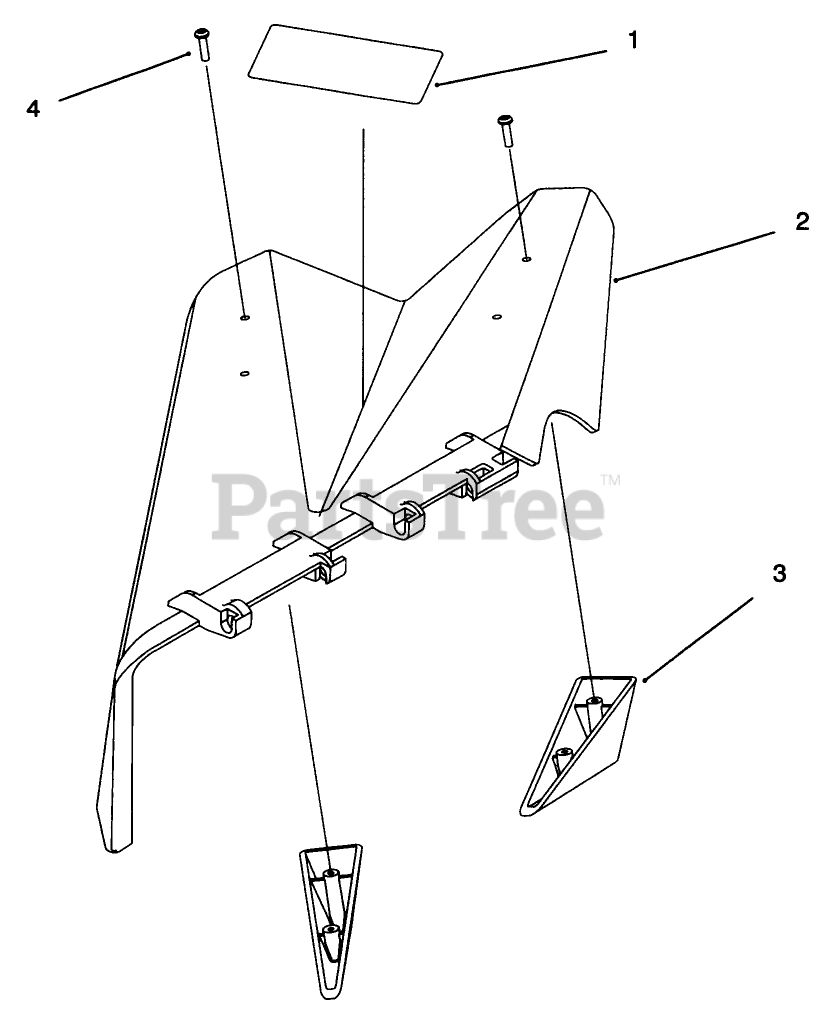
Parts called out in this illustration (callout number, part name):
1	DECAL-DANGER
3	KICKER
4	SCREW-PPH
